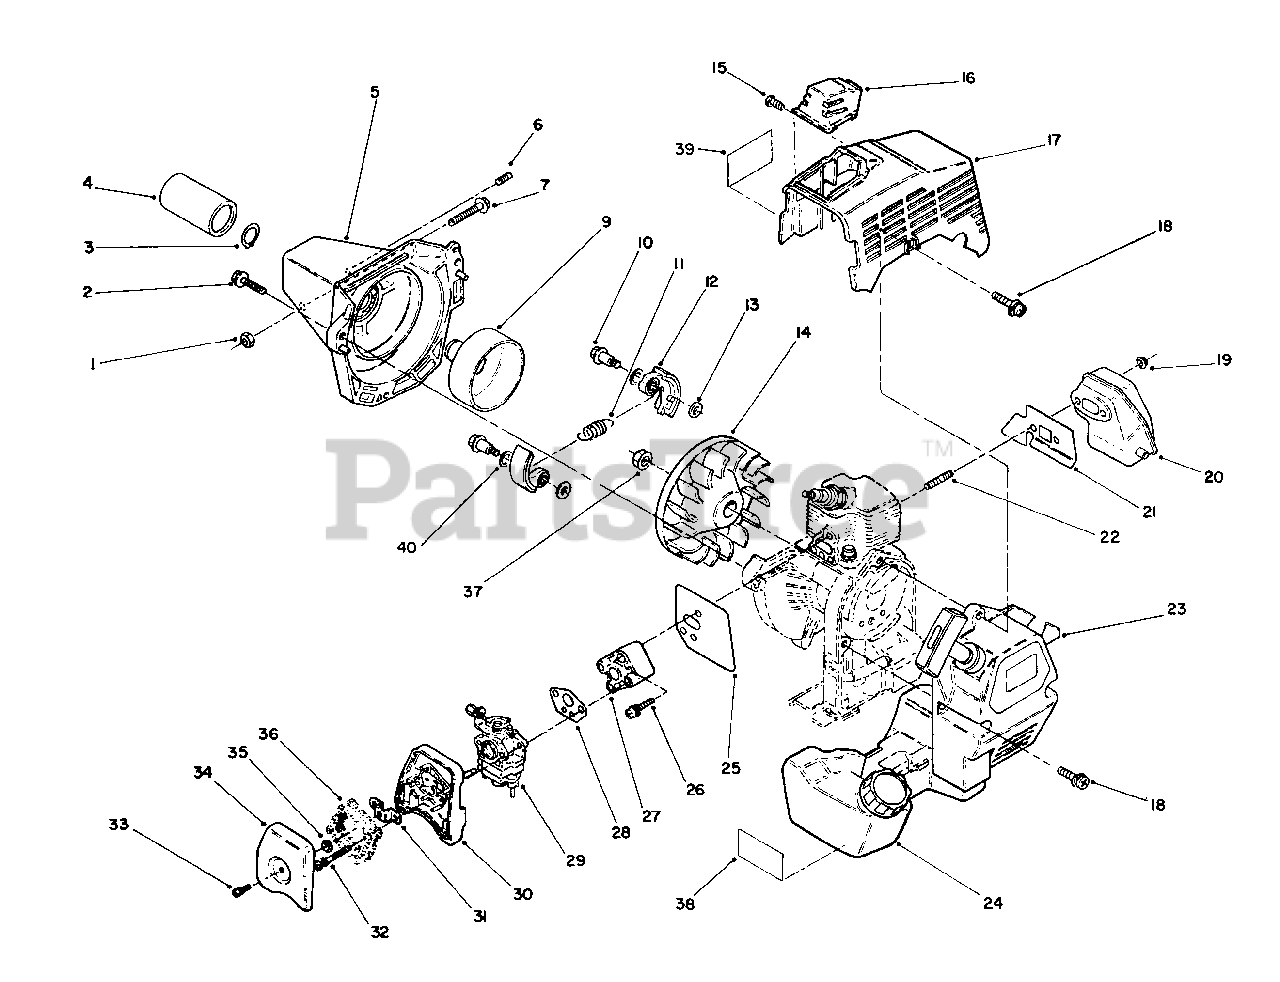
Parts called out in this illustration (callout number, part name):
1	Nut-Lock
2	Bolt/Washer
3	Ring-Retaining
5	Housing-Clutch
6	Screw-Set
7	Screw/Washer
9	Clutch-Drum
10	Bolt Clutch
11	Spring
12	Shoe-Clutch
14	Fan
16	Guard-Spark Plug
17	Cover-Engine
18	Screw/Washer
19	Nut-Flanged
21	Gasket-Muffler
23	Recoil Assembly
24	Fuel Tank Assembly
25	Gasket-Insulator
26	Screw/Washer
27	Insulator
28	Gasket-Carburetor
29	Carburetor Assembly
30	Case-Air Cleaner
31	Bracket-Cover
32	Screw/Washer
33	Screw/Washer
34	Cover-Air Cleaner
36	Element-Air Cleaner
37	Nut-Conical
38	Decal-Mix
39	Decal-Hot
40	Washer-Wave
